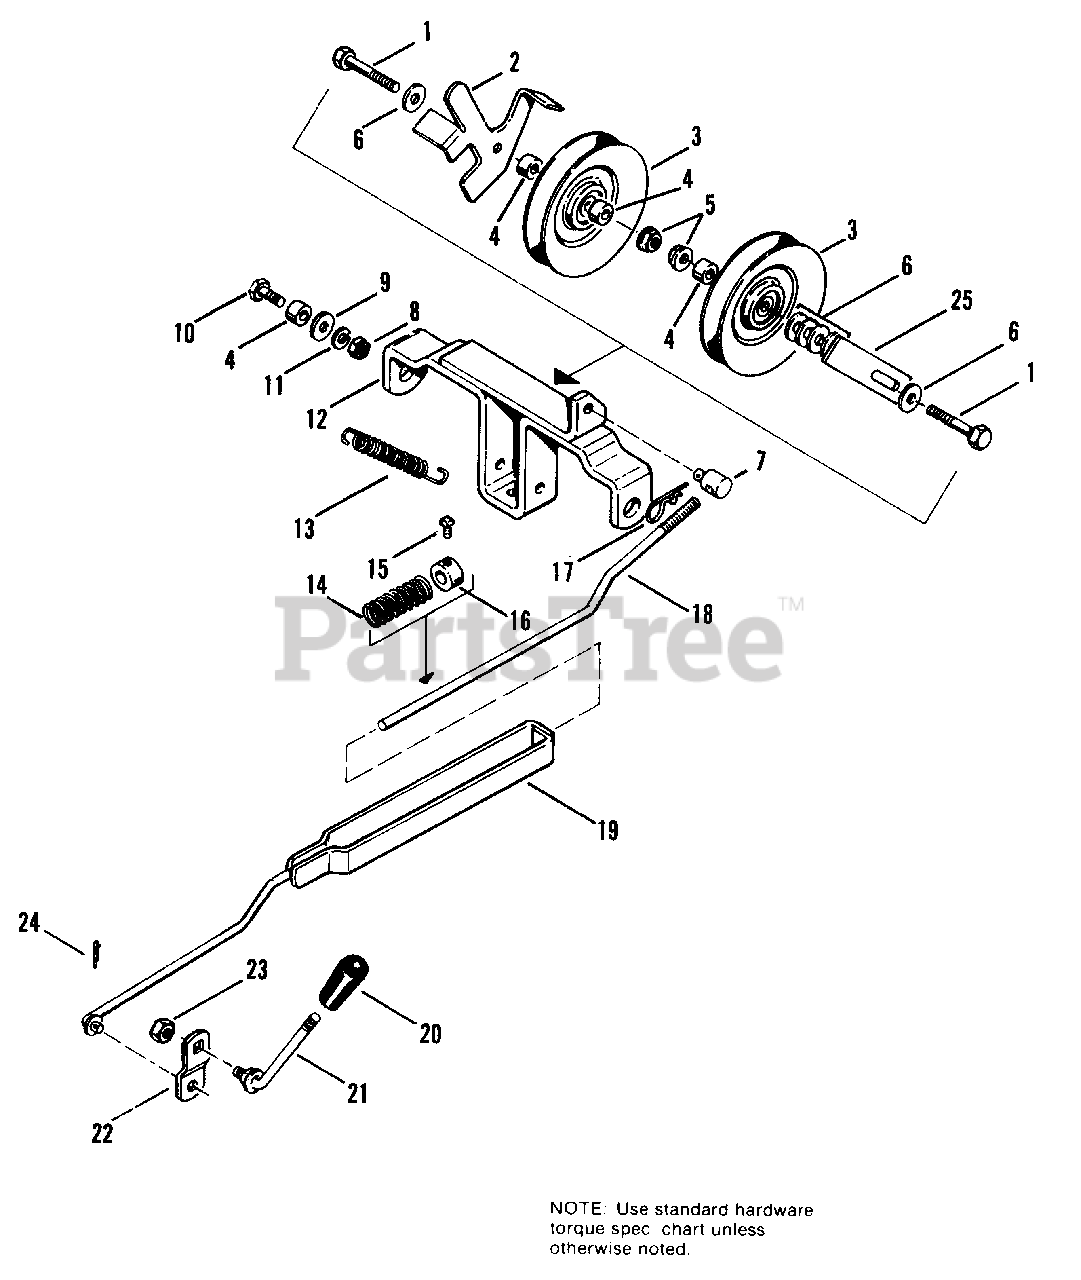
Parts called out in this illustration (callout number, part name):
1	CAPSCREW, Hex Hd., 3/8-16 x 2
3	PULLEY, Idler
5	LOCKNUT, Flange, 3/8-16
6	WASHER, Plain, 5/16
7	PIVOT, Rod End
8	NUT, Hex, Full, 3/8-16
9	WASHER, Plain, 3/8
10	CAPSCREW, Hex Hd., 3/8-16 x 1
11	LOCKWASHER, 3/8
12	CLEVIS ASSY., Pulley
13	SPRING
15	SETSCREW, 1/4-20 x 3/8
16	COLLAR, Set
17	CLIP, Spring
19	GUIDE ASSY., P.T.O.
20	KNOB
21	HANDLE, Clutch Control
22	ARM, P.T.O.
23	LOCKNUT, Hex, 3/8-16
24	PIN, Cotter, 3/32 x 5/8
